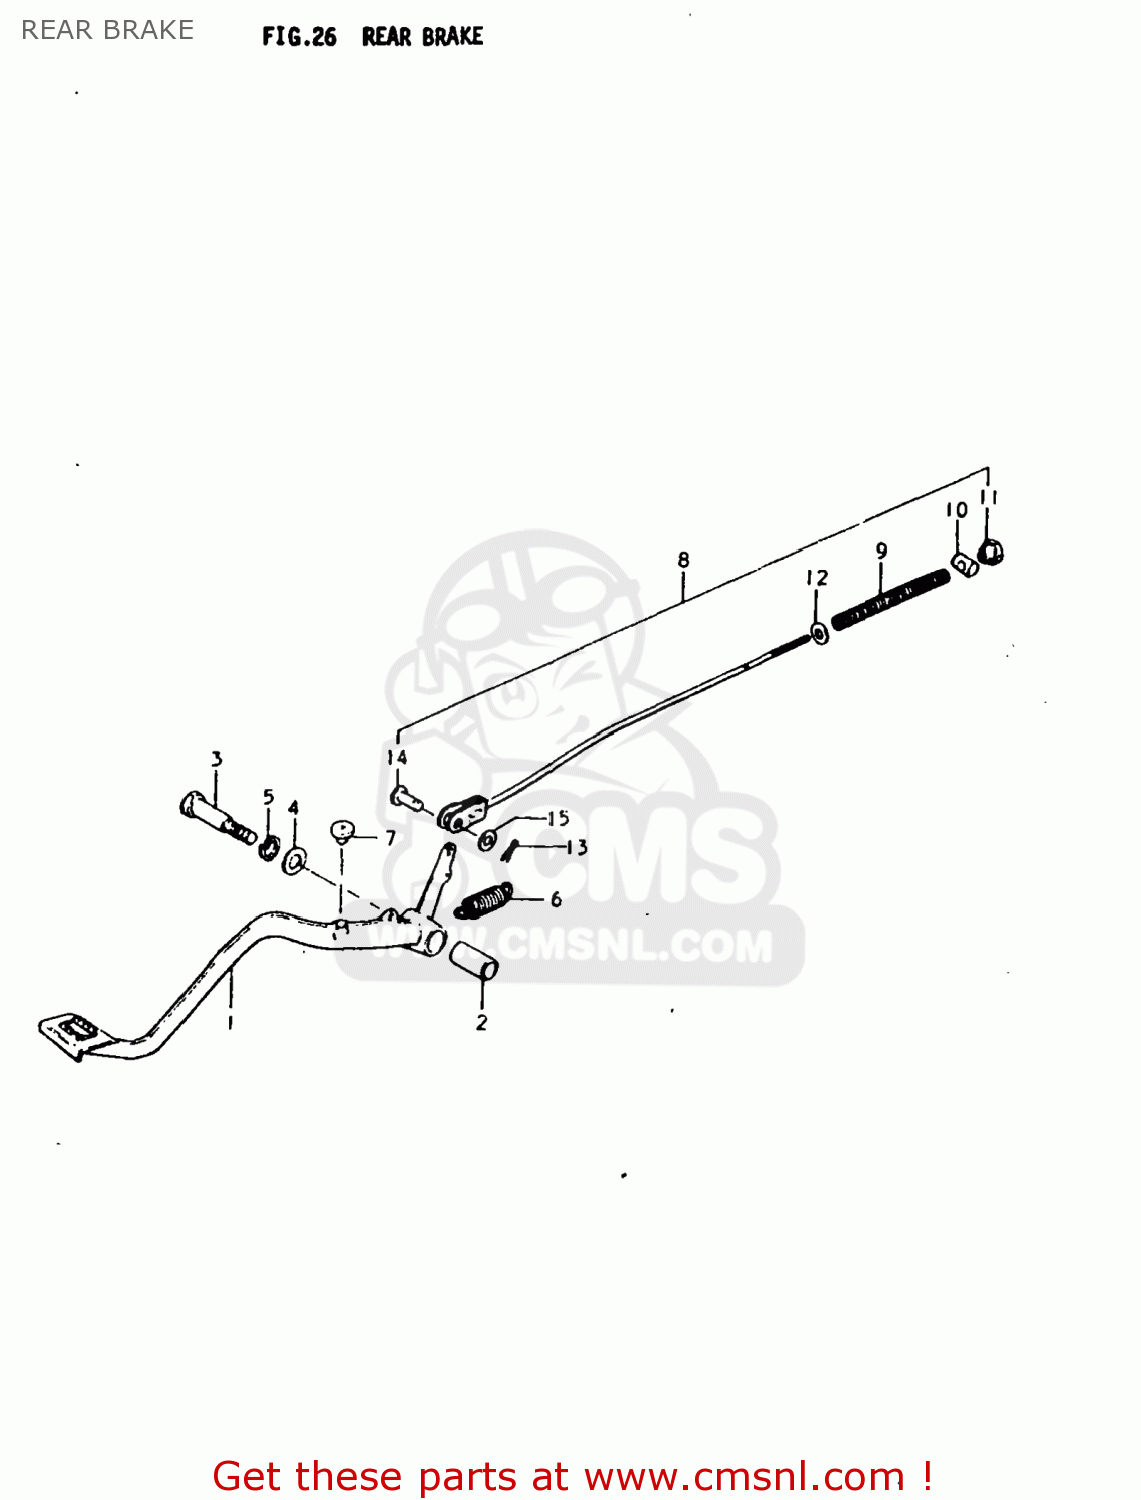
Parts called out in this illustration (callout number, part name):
1	PEDAL,BRAKE
2	SPACER(10.5X16X30)
3	BOLT
4	WASHER
5	LOCK WASHER
6	SPRING
7	STOPPER,BRAKE PEDAL
8	ROD ASSEMBLY,REAR BRAKE
9	SPRING
10	PIN
11	NUT
12	WASHER
13	PIN 20X20
14	PIN(L:13.5)
15	WASHER
